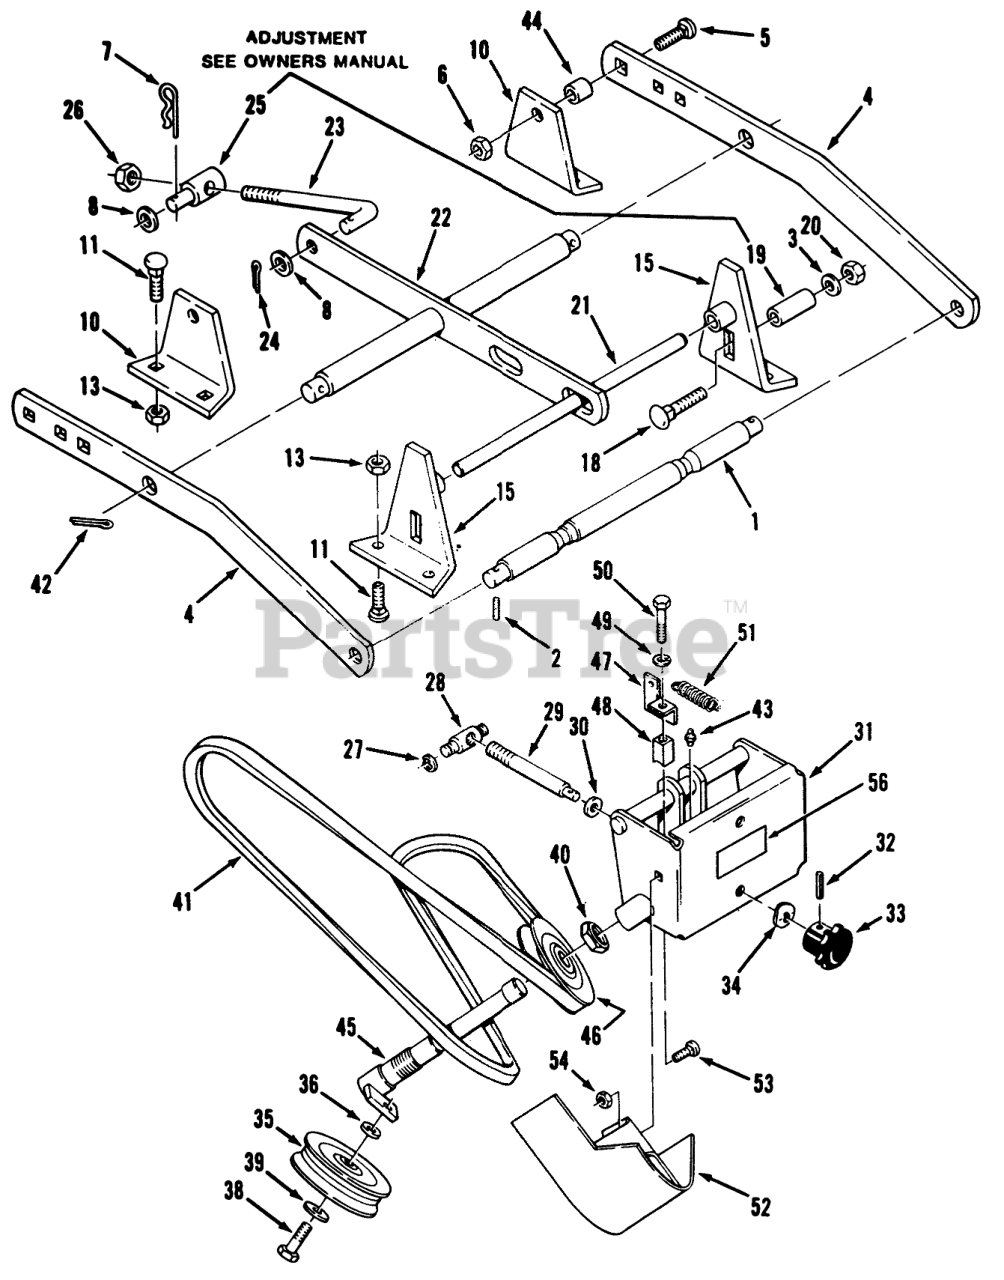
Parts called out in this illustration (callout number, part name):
1	Shaft
3	Washer
4	Bar-Draft
5	BOLT-CARR
6	LOCKNUT-FLANGE
7	Hairpin
8	WASHER-FLAT
10	Rear Deck Bracket
11	BOLT-CARR
13	NUT-LOCK, NI
15	Front Deck Bracket
18	BOLT-CARR
19	SPACER
20	Nut
21	Front Shaft
22	Leveler
23	ROD LEVELER
24	PIN-COTTER
25	TRUNION
26	NUT-LOCK, NI
27	RING-RETAINING
28	TRUNNION-DOUBLE
29	ROD ADJ
30	WASHER-FLAT
31	Front Idler Support
32	PIN-ROLL
33	KNOB-ADJUSTMENT
34	WASHER-SPRING
35	PULLEY-FLAT IDLER
36	SPACER
38	SCREW-HH
39	WASHER-FLAT
40	NUT-JAM
41	BELT-103" A SECTION
42	PIN-COTTER
43	FITTING-GREASE
44	SPACER
45	ASS'Y-IDLER ARM
46	Pulley-V
47	Bracket
48	BLOCK-GUIDE
49	WASHER-LOCK
50	SCREW-HH
51	SPRING-BRAKE
52	Cover
53	BOLT-CARR
54	NUT-LOCK, NI
56	Decal-Attac-O-Matic
